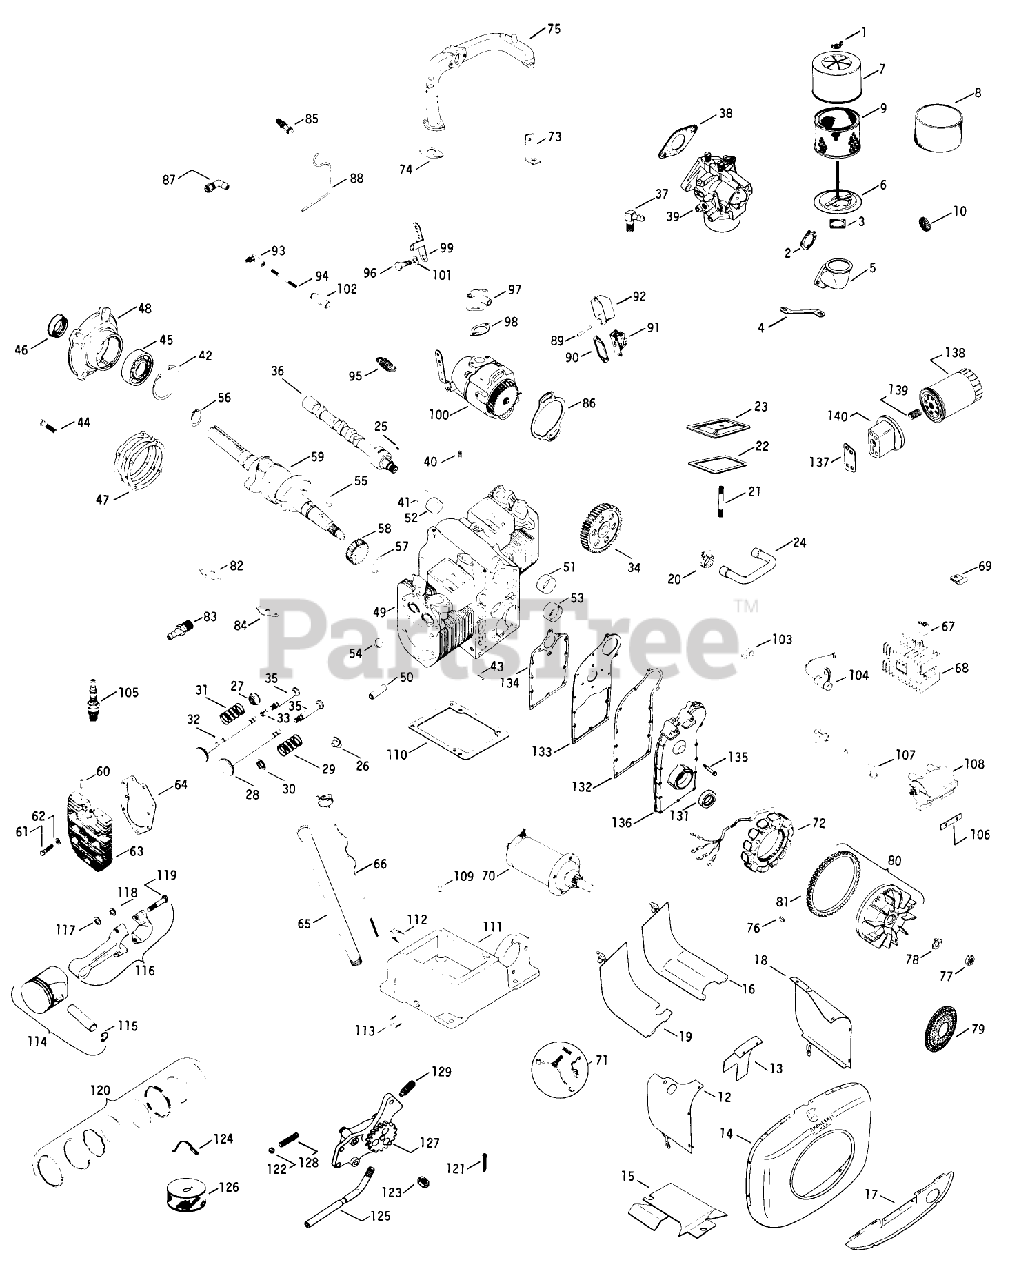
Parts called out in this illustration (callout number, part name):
1	Nut-Wing
2	Gasket
3	Gasket-Air Cleaner
4	Brace elbow
5	Elbow air cleaner
6	Base-Air Cleaner
7	Cover-Air Cleaner
8	Element
9	Element
10	Screen
12	Baffle #1 Cyl. Hd.
13	Baffle, #1 Upper Cyl.
14	Housing, Blower
15	Baffle
16	Baffle #2 Barrel
17	Baffle-Housing Support
18	Baffle #2 cylinder head
19	Baffle, #1 barrel
20	Clamp-Hose
21	Stud, valve cover
22	Gasket-Valve Cover
23	Cover-Valve
24	Hose-Breather
25	Key-Woodruff
26	Retainer-Spring
27	Rotator
28	Valve-Intake
29	Spring
30	Retainer-Spring
31	Spring
32	Valve exhaust
33	Keeper, Valve
34	Gear, Camshaft
35	Tappet
36	Camshaft
37	Elbow
38	Gasket
39	Carburetor-assembly (Replaced by 48 053 12)
39	Repairkit
39	Repair kit, choke (Not used prior to serial no. 6373502)
40	Plug
40	Plug, Pipe
41	Plug-Welch
42	Pin
43	Pin
44	Screw-H.C.
45	Bearing-Ball
46	Seal-Rear Oil
47	Gasket-Closure Plate
48	Plate, rear closure
49	Crankcase-assembly
50	Guide Valve
51	Bushing
52	Bushing
53	Bearing
54	Insert
55	Key
56	Ring-Retaining
57	Ring-Retaining
58	Gear, crankshaft
59	Crankshaft
60	Pin, Roll 3/16x1-1/8
61	Screw
62	Washer
63	Head, Cylinder
64	Gasket, Cylinder Head
65	Tube, dipstick
66	Dipstick
67	Connector
68	Regulator
69	Clip
70	Starter Assembly
71	Kit, Brush
72	Stator
73	Lift Cable
74	Gasket
75	Manifold, Intake
76	Key-Woodruff
77	Nut-Hex.
78	Nut-Lock
79	Screen, grass
80	Flywheel-assembly
81	Gear, Ring
82	Gasket, pump
83	Connector
84	Cover, fuel pump
85	Connector
86	Gasket-Governor Housing
87	Elbow
88	Line, Oil
89	Rod, Breaker Push
90	Gasket, Cover
91	Breaker
92	Cover
93	Ball Joint
94	Rod-Throttle
95	Spring Governor
96	Screw Shoulder
97	Housing, breather (Includes valve)
98	Gasket
99	Lever-Throttle
100	Governor
101	Washer
102	Ball Joint
103	Clip-Cable
104	Condenser
105	Plug, spark
106	Plate Coil Mounting
107	Lead high tension
108	Coil
109	Pin-Dowel
110	Gasket-Oil Pan
111	Pan, oil-assembly
112	Plug
113	Plug, Pine
114	Piston-assembly (Std.) (Includes pin retainers)
114	Piston-assembly (.003) (Includes pin retainers)
114	Piston-assembly (.010) (Includes pin retainers)
114	Piston-assembly (.020)(Includes pin retainers)
114	Piston-assembly (.030) (Includes pin retainers)
115	Pin, Retainer
116	Rod, conn.-assembly (Std.)
116	Rod, Connecting (.010 U.S.)
117	Washer
118	Washer
119	Screw, connecting rod
120	Ring set (Std. .003)(Svc)
120	Ring Set-.010 (Service)
120	Ring set(.020)(Service)
120	Ring Set-.030 (Service)
121	Pin-Cotter
122	Ball Steel
123	Palnut
124	Clip-Oil Tube
125	Tube-Oil Inlet
126	Strainer-Oil
127	Pump
128	Spring, Relief Valve
129	Screw
131	Seal rear oil
132	Gasket-Gear Cover
133	Plate-Gear Cover
134	Gasket-Gear Cover Plate
135	Screw-H.C.
136	Cover, gear
137	Gasket, adapter
138	Filter-Oil
139	Nipple
140	Adapter, filter
